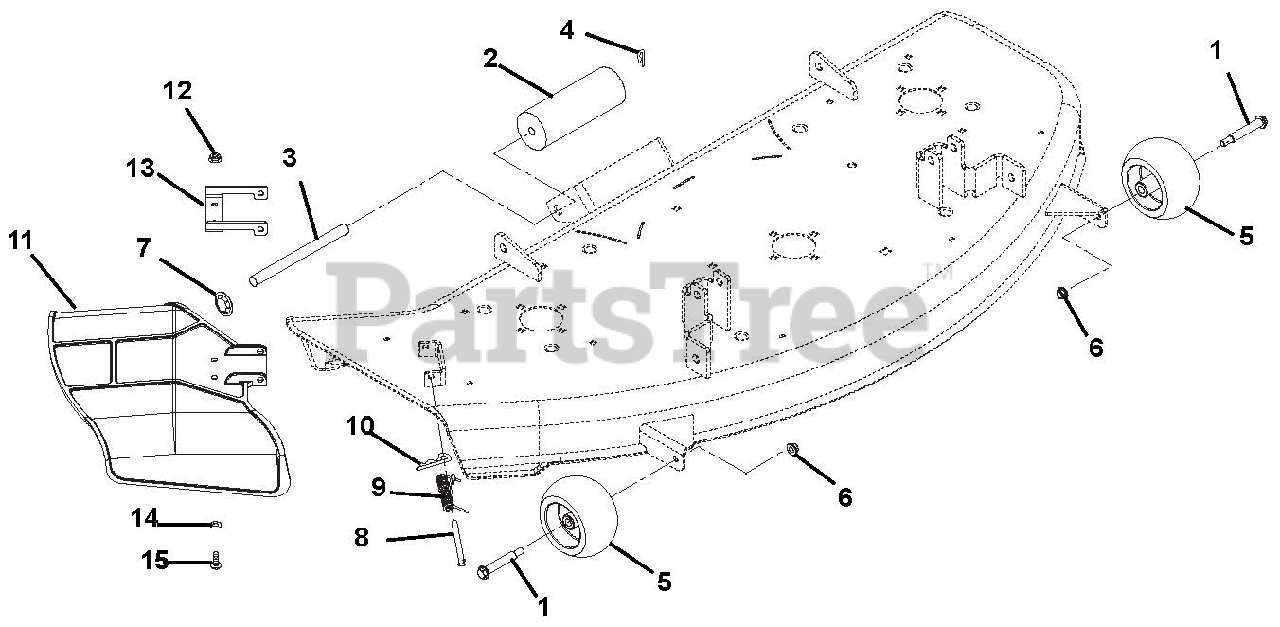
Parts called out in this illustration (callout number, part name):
1	BLT-SHLDR .38-16X2.50 HWH G5
3	PIN, ROLLER
4	PIN, SPRING CLIP
5	ANTI-SCALP WHEEL - 5X OS
6	@NUT-LK-TOP-FLG .38-16 YWZC
7	PUSH NUT, .625 SHAFT
8	PIN, 5/16 X 3.88"
9	SPACER, .390X.75X.146
10	PIN-HAIR INT .08X.18X1.18 YWZC
11	CHUTE, SIDE DISCHARGE
12	@NUT-LK-TOP-FLG .31-18 YWZC
13	CHUTE REINFORCEMENT
14	@WSHR-FL-STL.38X.875X.083 YWZC
15	SCR-SKH .31-18X.75 BTNHD YWZC
